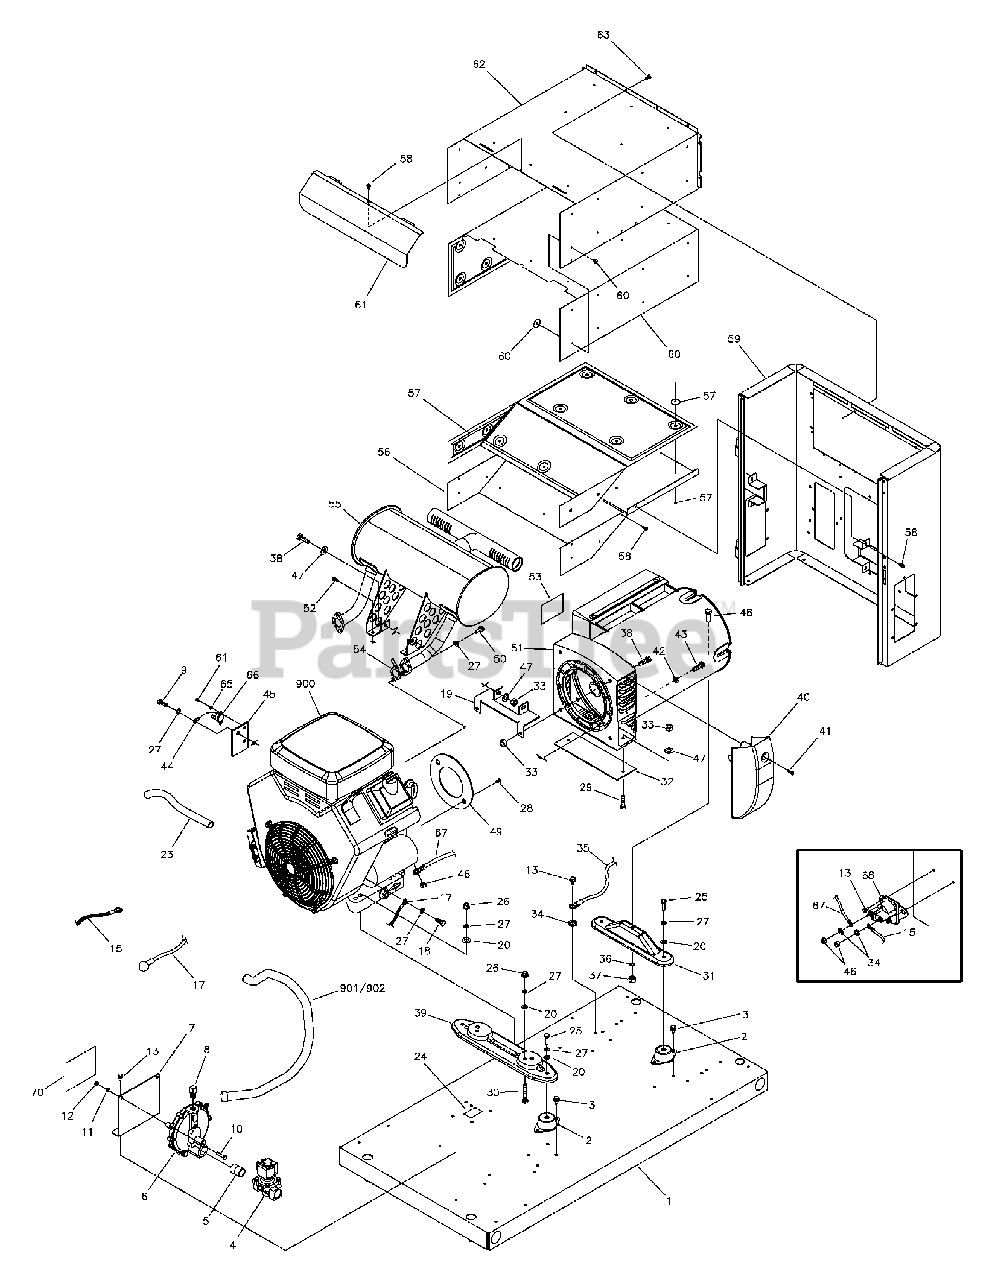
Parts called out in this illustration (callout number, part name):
2	MOUNT, Vibration
4	SOLENOID, Gas Fuel
6	REGULATOR, NG / LPG
7	BRACKET
9	* CAPSCREW, Hex Head, M8 - 1-1/4 x 12
10	* CAPSCREW, Hex Head, M6 - 1 x 30
11	* WASHER, Lock, 1/4
12	* NUT, M6 - 1
13	BOLT
18	* CAPSCREW, Hex Head, M8 - 1-1/4 x 16
20	* WASHER, Flat, 5/16 - M8
23	HOSE, Oil Drain
24	DECAL, Oil Drain
25	* CAPSCREW, Hex Head, 5/16-18 x 1
26	* NUT, 5/16-18
27	* WASHER, Lock, 5/16 - M8
28	* CAPSCREW, Hex Head, SEMS, 5/16-24 x 3/4
29	* CAPSCREW, Hex Head, 1/4-20 x 1
30	* CAPSCREW, Hex Head, 5/16-18 x 1-3/4
31	SUPPORT, Alternator
34	* WASHER, Shakeproof, EXT M6 - 1/4
36	* WASHER, Lock, M10
37	* NUT, Hex, M10 - 1-1/2
38	* CAPSCREW, Hex Head, 1/4-20 x 3/4
39	SUPPORT, Alternator
42	* WASHER, Lock, 3/8
43	* CAPSCREW, Hex Head, 3/8-16 x 1-1/4
45	PLATE, Temp Switch
46	* NUT, Hex, 1/4-20
47	* WASHER, Flat, M6 - 1/4
48	* CAPSCREW, Hex Head, M10 - 1-1/2
51	ALTERNATOR ASSEMBLY
52	CAPSCREW, M8 - 1-1/4 x 20
59	BULKHEAD, Alternator
62	BOX, Muffler Top
64	* SCREW, Phillips Head, 4-40 x 0.19
65	* WASHER, Lock, #4
66	SWITCH, Temp
68	SOLENOID, Starter
70	DECAL, Fuel Requirements
900	** ENGINE
901	FUEL HOSE
